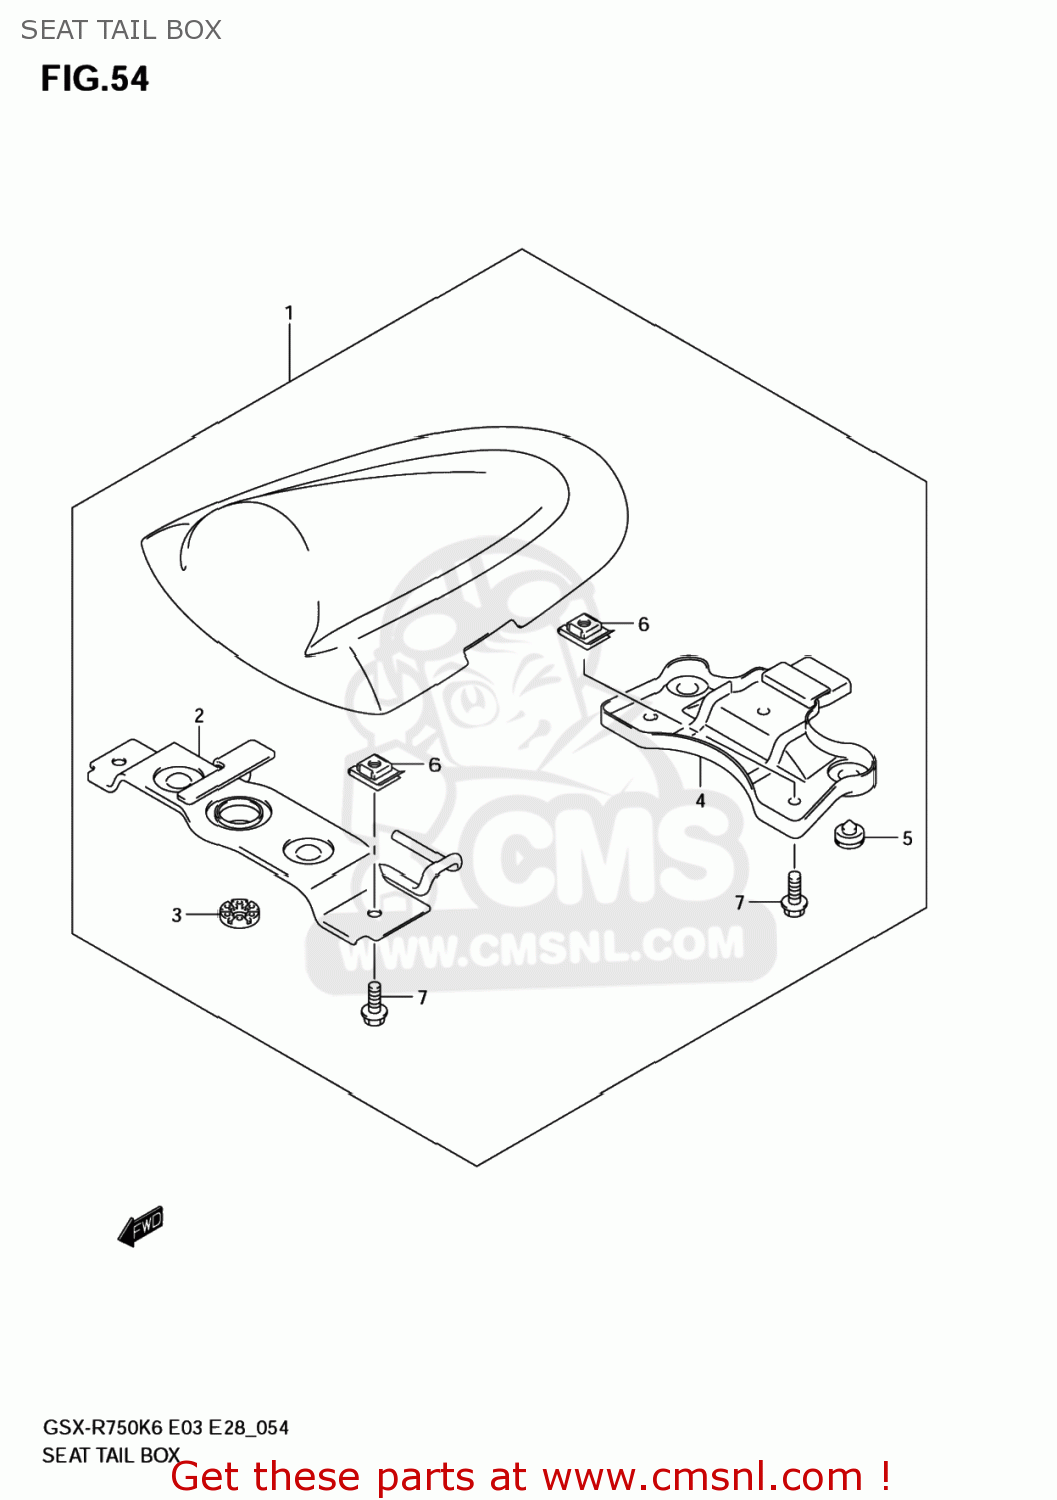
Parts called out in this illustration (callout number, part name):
1	BOX,SEAT TAIL
2	STRIKER
3	CUSHION
4	BOTTOM
5	CUSHION,FR
6	NUT
7	BOLT
